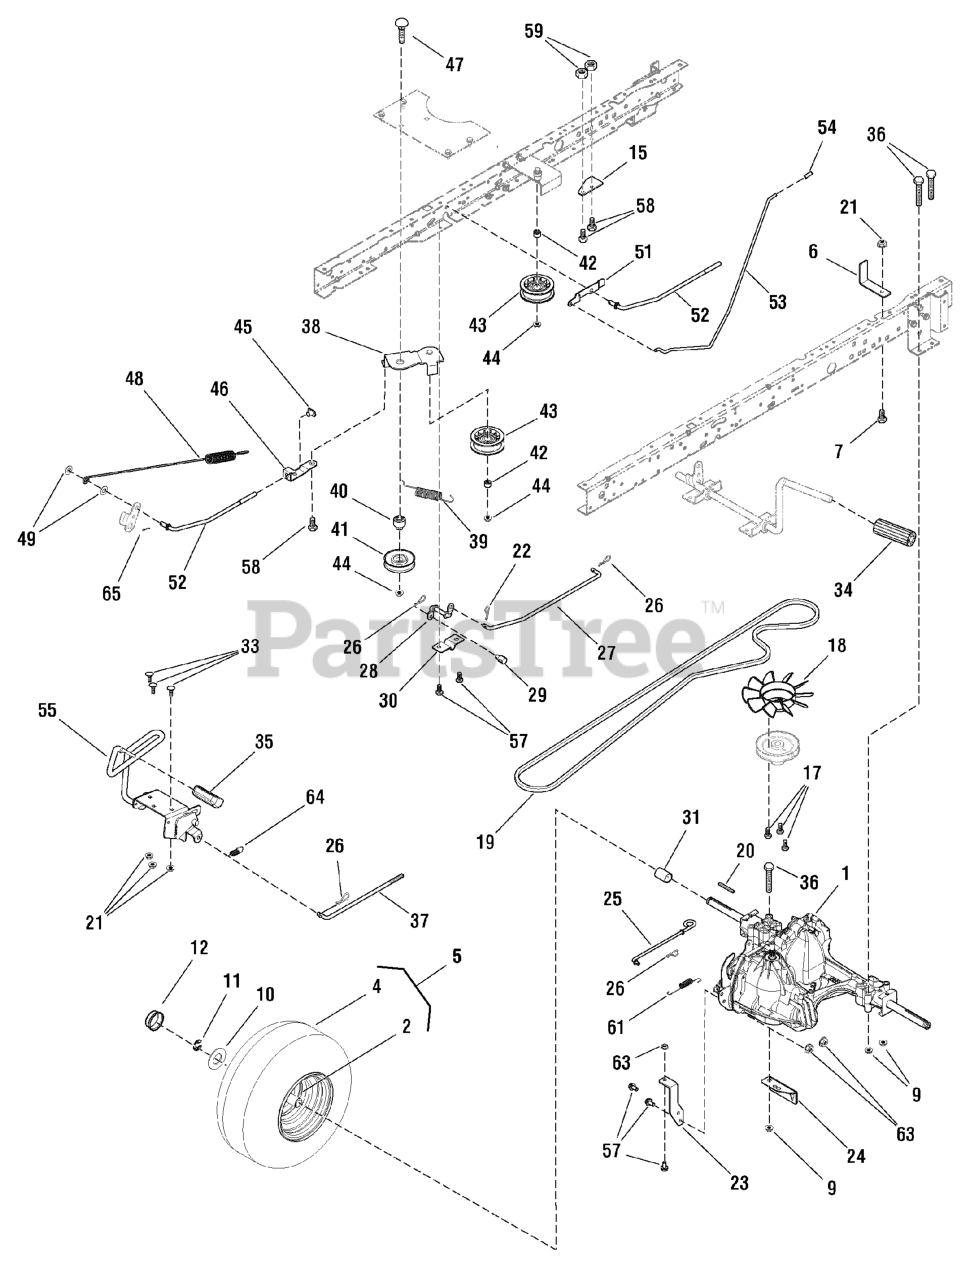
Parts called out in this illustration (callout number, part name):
1	TRANSAXLE, Hydro Gear
2	VALVE STEM, TR412
4	TIRE, 20 x 10-8, 2 Ply K358
5	WHEEL & TIRE ASSY, 20 x 10.0-8
6	GUIDE, Hydro Belt
7	BOLT, Hex, 5/16-18 x 2-1/2
9	NUT, Hex Flange 5/16-18
10	WASHER, Flat 1-3/4
11	E-RING, .750D-.050T
12	HUB CAP
15	PLATE, Forward Stop
17	SCREW, #12-24 x 1/2
19	BELT, Dual Spindle Brake
20	KEY, Square, 3/16
21	NUT, Hex Flange, 5/16-18
22	PIN, Cotter, 3/4
23	BRACKET, Torque, Hydro
24	BRACKET, Roll Release
25	LEVER, Roll Release
26	HAIR PIN
27	ROD, Rear Drive
28	ROD, Pivot Drive
29	SWIVEL, Adjustable
30	BRACKET, Support
31	SPACER, Axle
33	BOLT, Carriage, 3/8-16 x 5/8
34	PEDAL, Clutch and Brake
35	PAD, Foot Pedal, Forward
36	BOLT, Hex 5/16-18 x 2 1/2
37	ROD, Front Drive
38	ARM ASSEMBLY, Idler
39	SPRING, Extension Control
40	BUSHING, Pivot
41	PULLEY, Idler, 3 in
42	SPACER, 1/2 in To 17 mm
43	PULLEY, Idler, 2-3/4 in
44	NUT, Flange Lock, 3/8-16
45	NUT, Tee
46	LINK, Clutch, Yellow
47	BOLT, Carriage, 3/8-16 x 2
48	SPRING, Hydro Brake
49	WASHER, Flat 1
51	LATCH, Parking Brake
52	ROD, Clutch Drive
53	ROD, Parking Brake
55	FOOT CONTROL
57	BOLT, Hex Flange, 5/16-16 x 5/8
58	SCREW, Hex 1/4-20 x 5/8
59	NUT, Nylock 1/4-20
61	SPRING, Extension
63	NUT, Hex Flange, 5/16-18
64	SPRING, Extension
65	PIN, Cotter
